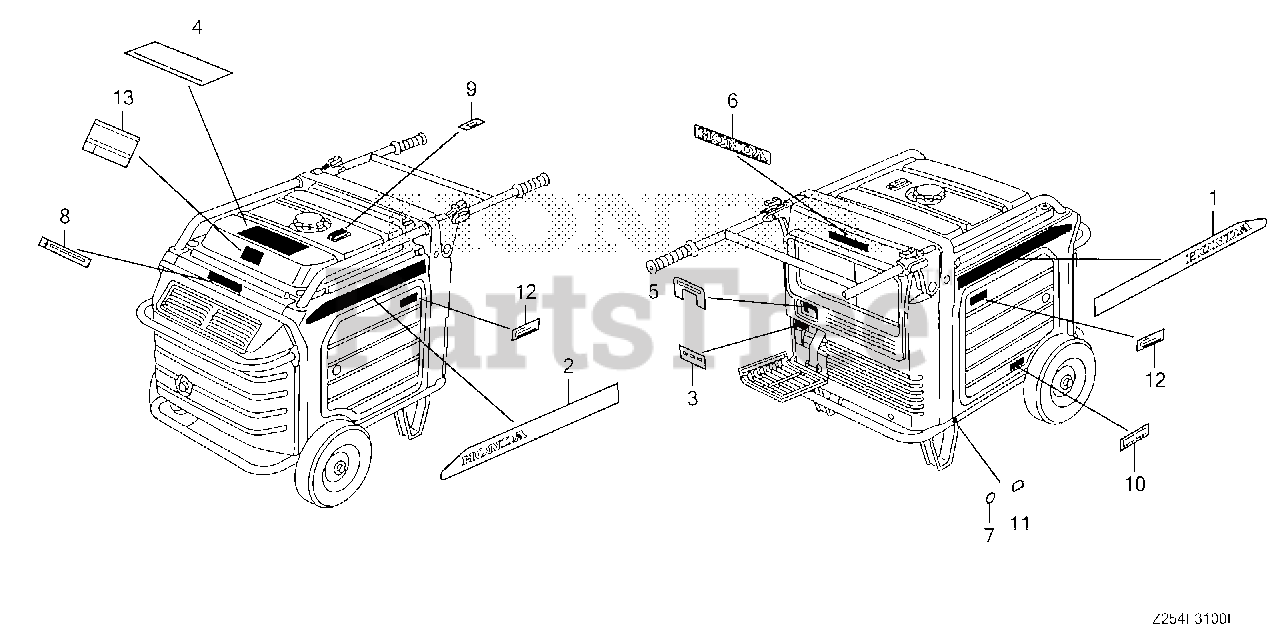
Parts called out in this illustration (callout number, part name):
1	MARK, EMBLEM (R)
2	MARK, EMBLEM (L)
3	MARK, BRANCH FUSE (E)
4	MARK, CAUTION (E)
4	LABEL, OPERATOR WARNING (E)
5	MARK, PANEL SWITCH
6	MARK, HONDA
7	MARK, GROUND
8	MARK, EX. CAUTION
9	PLATE, FUEL INDICATION
10	MARK, OIL CAUTION
